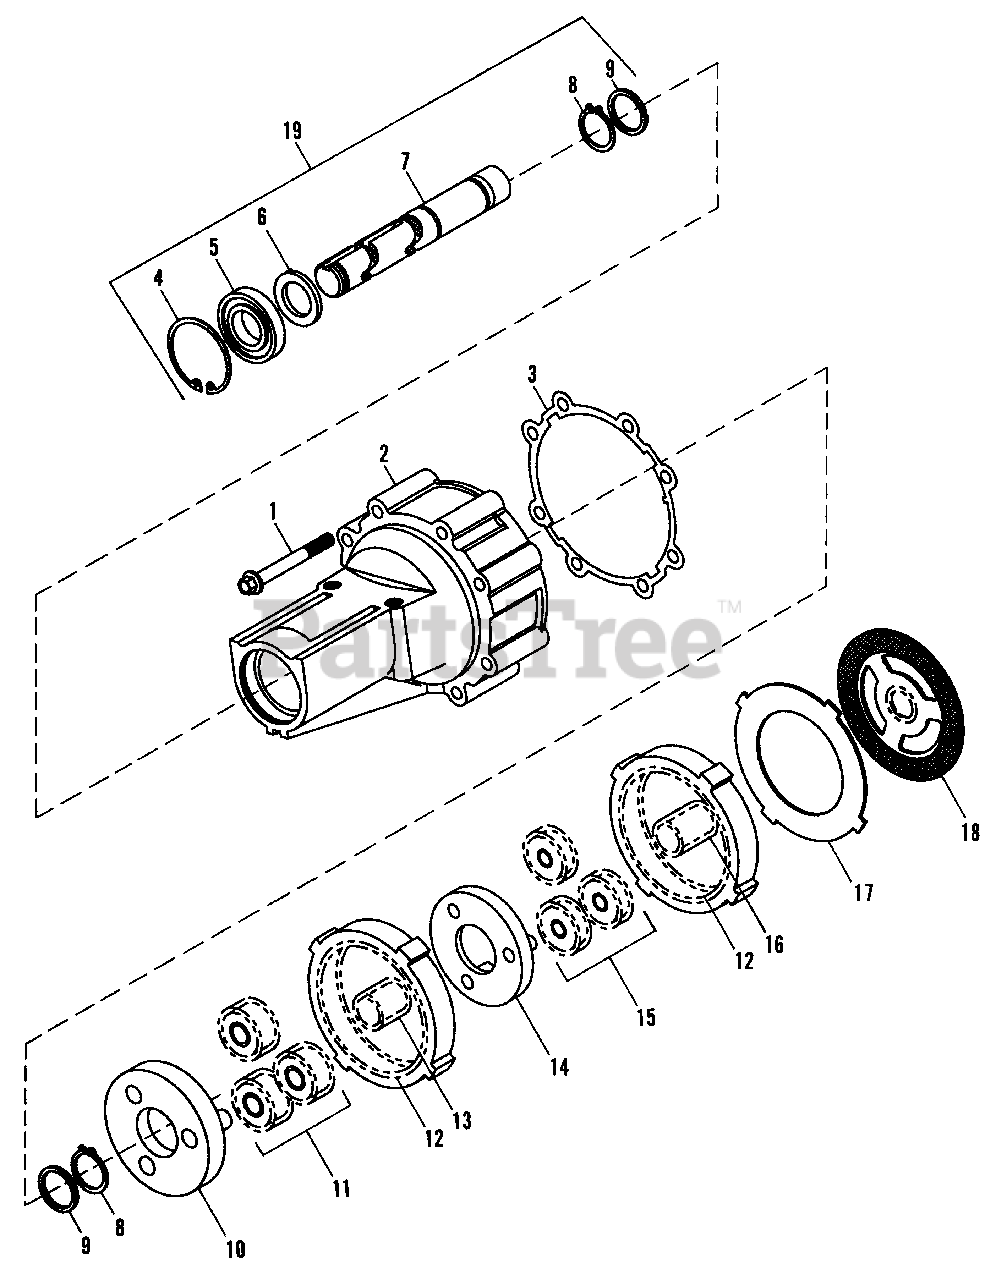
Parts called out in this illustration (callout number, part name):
1	SCREW, .25-20 Hex Flg.
2	HOUSING, Axle
3	AXLE HOUSING GASKET
4	RING, Ret., Internal
5	BEARING, Ball
6	SEAL, Radial Lip
7	SHAFT, Aide
8	RING, Retainer
9	WASHER, Thrust
10	SECONDARY CARRIER
11	GEAR, Second, 18 Teeth
12	GEAR, Ring, 54 Teeth
13	SUN GEAR, Second, 18 Teeth
14	PRIMARY CARRIER, 18 Teeth
15	GEAR, First, 18 Teeth
16	GEAR, First, 18 Teeth
17	PLATE, Back-up
18	PLATE, Reaction
19	AXLE HOUSING ASSY. (Contains Ref. Nos. 2, 4-9)
